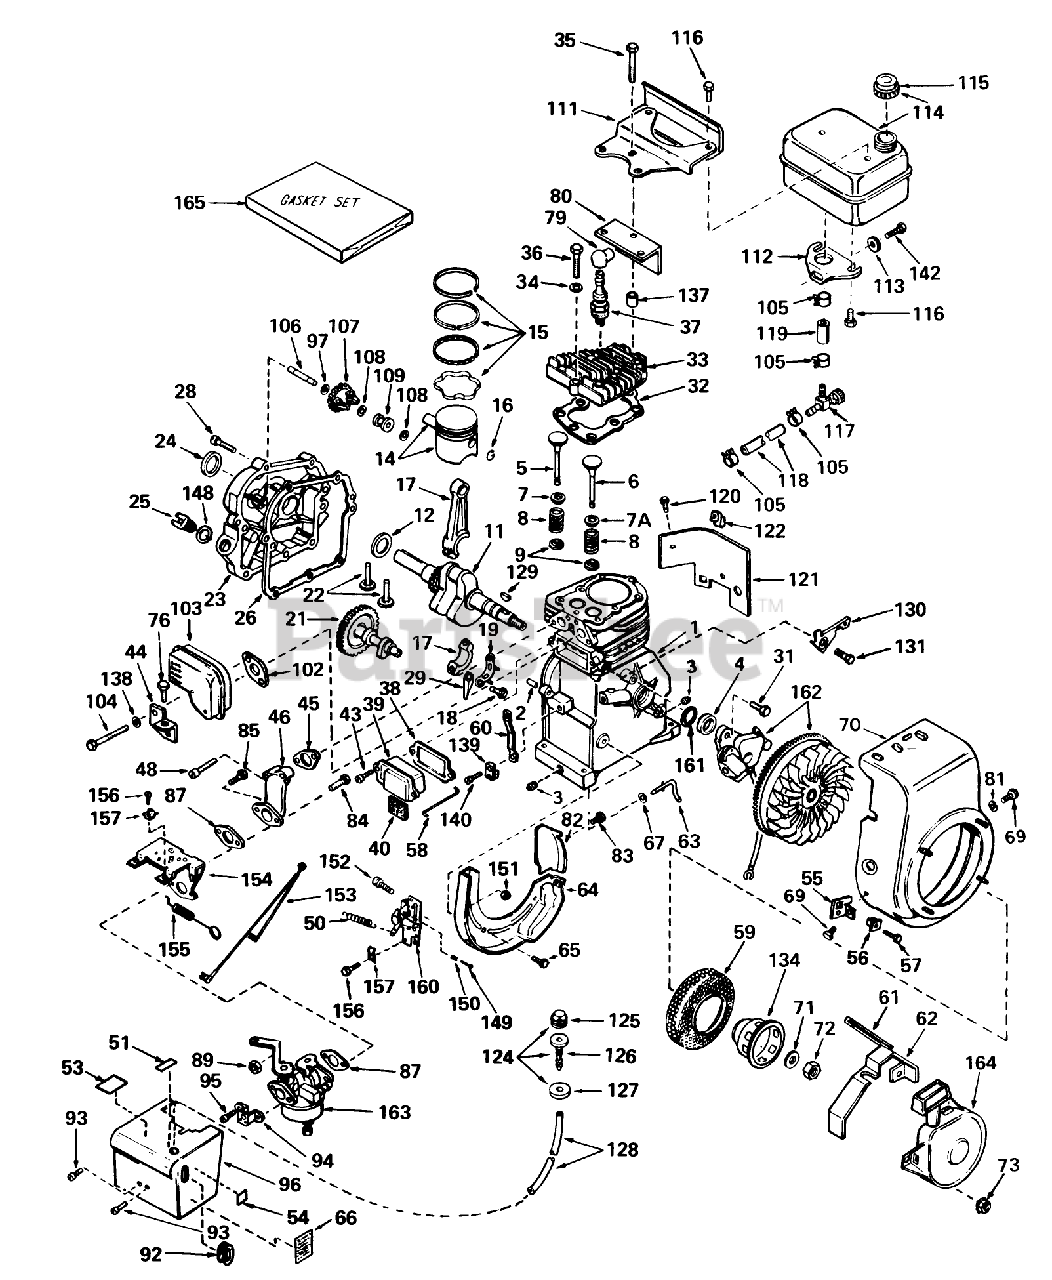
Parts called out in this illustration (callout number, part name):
1	Cylinder Assy. (Incl. Nos.2, 34)
2	Pin-Dowel
3	Plug-Drain, Oil (SQH 1/4-18)
4	Seal-Oil
5	Valve, Intake (Standard) (Incl. Nos. 7, 9 10)
5	Valve, Intake (1/32" Oversize) (Incl. Nos. 7, 9 10)
6	Valve, Exhaust (Standard) (Incl. Nos. 8, 9 10)
6	Valve, Exhaust (1/32" Oversize) (Incl. Nos. 8, 9 10)
7	Cap-Upper Valve Spring
7A	Cap, Upper Valve Spg (Exhaust)
8	Spring-Valve
9	Cap-Valve, Spring
11	Crankshaft Assy.
12	Washer-Thrust
14	Piston Pin Assembly (Incl. 2 of No. 14)(Std.)
14	Piston Pin Assembly (Incl. 2 of No. 14)(.010 Oversize)
14	Piston Pin Assembly (Incl. 2 of No. 14)(.020 Oversize)
15	Ring Set-Piston Std.
15	Ring Set-Piston .010 oversize
15	Ring Set-Piston .020 oversize
16	Ring-Retaining, Piston Pin
17	Rod Assy., Connecting (Incl. Nos. 18 19)
18	Connecting Rod Bolt
19	Plate Lock
21	Camshaft
22	Lifter-Valve
23	Cover, Cylinder (Incl. Nos. 24, 25, 106 148)
24	Seal-Oil
25	Plug-Fill, Oil
26	Gasket-Cylinder Cover
28	Screw
29	Dipper-Oil
31	Screw
32	Oil Fill Tube
33	Head Cylinder
34	Washer
35	Screw Hex Hd. Cap
36	Screw
37	Plug, Spark (Champion RCJ8 or Autolite AR7N Resistor type)
38	Gasket Breather
39	Breather Assembly (Incl. Nos. 52 84)
40	Element-Breather
43	Screw
44	Bracket-Cover, Carburetor
45	Gasket-Intake
46	Pipe-Intake
48	Screw (1/4-20 x 1-19/32)
50	Spring-Extension
51	Decal-Primer
53	Decal, Warning
54	Decal, "Choke"
55	Bracket
56	Grommet
57	Screw
58	Link-Governor to Throttle
59	Screen-Starter
60	Lever, Governor
61	Seal, Snowguard
62	Guard-Starter
63	Rod-Governor
64	Baffle-Blower Housing
65	Screw (1/4-20x19/32)
66	Decal, Instruction
67	Washer-Flat
69	Screw
70	Housing, Blower
71	Washer-Spring
72	Hex Nut
73	Nut and Lock Washer (1/4-28)
76	Screw (10-24 x 3/8)
79	Cover-Spark Plug
80	Baffle-Heat
81	Washer
82	Baffle-Extension
83	Screw-Hex Washer Hd.
85	Screw-Fil. Hd.
87	Gasket
89	Nut and Lock Washer (1/4-28)
92	Grommet, Carburetor cover
93	Screw (8-32 X 5/16)
94	Bracket-Choke
95	Screw (10-32 x 1/2)
96	Cover, Carburetor
97	Washer-Flat
102	Gasket-Exhaust
103	Muffler
104	Screw-Fil. Hd.
105	Clamp-Line, Fuel
106	Shaft-Governor
107	Governor Gear ASM
108	Ring-Retaining
109	Spool-Governor
111	Plate-Fuel Tank
112	Bracket, Fuel Tank Lower
113	Washer
114	53023/VAR.10/16HP O
115	Cap, Fuel
116	Screw (1/4-15x7/8)
117	Valve-Shut Off
118	Line-Fuel
119	Line-Fuel (8.62)
120	Screw
121	Extension-Blower
122	51004 GIL ROTARY TI
124	Primer Assy. (Incl. Nos. 89, 90 91)
125	Bulb, Primer
126	Body, Primer
127	Retainer, Primer Bulb
128	Line, Primer
129	Key, FIywheel
130	Bracket-Hold Down
131	Screw, Hex Hd. w/Conical
134	Cup, Starter
137	pacer
138	Washer
139	Clamp-Lever, Governor
140	Screw
142	Screw (1/4-20 X 5/8)
148	Gasket
149	Screw
150	Spring-Compression
151	Nut-Lock
152	Screw
153	Wire, Ground
154	Bracket, Speed Control
155	51011/13 TILL.O/P'7
156	Screw (10-32 x 3/8)
157	Conduit
160	Bracket Assy., Control (Incl. Nos. 149, 150, 151 152)
161	Gasket Stator
162	Magneto
163	Carburetor (Incl. 1 of No. 87)
164	Starter Assy., Rewind
165	Gasket Set
